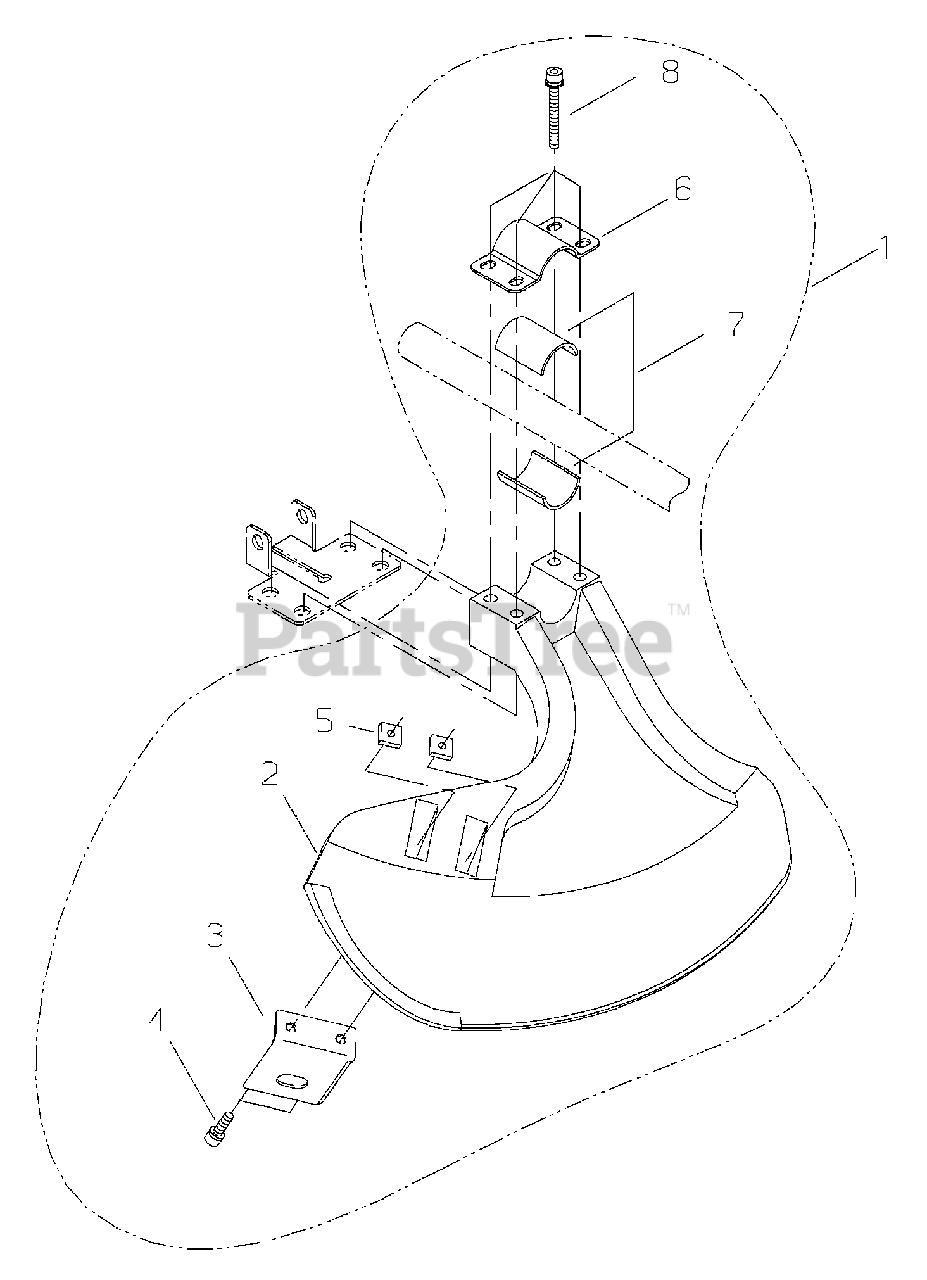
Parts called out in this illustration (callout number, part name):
1	DEBRIS SHIELD KIT
2	SHIELD, DEBRIS
3	KNIFE, TRIMMER LINE
4	SCREW - 5X16
5	NUT - 5
6	CLAMP - UPPER
7	SPACER
8	SCREW - 5X45
